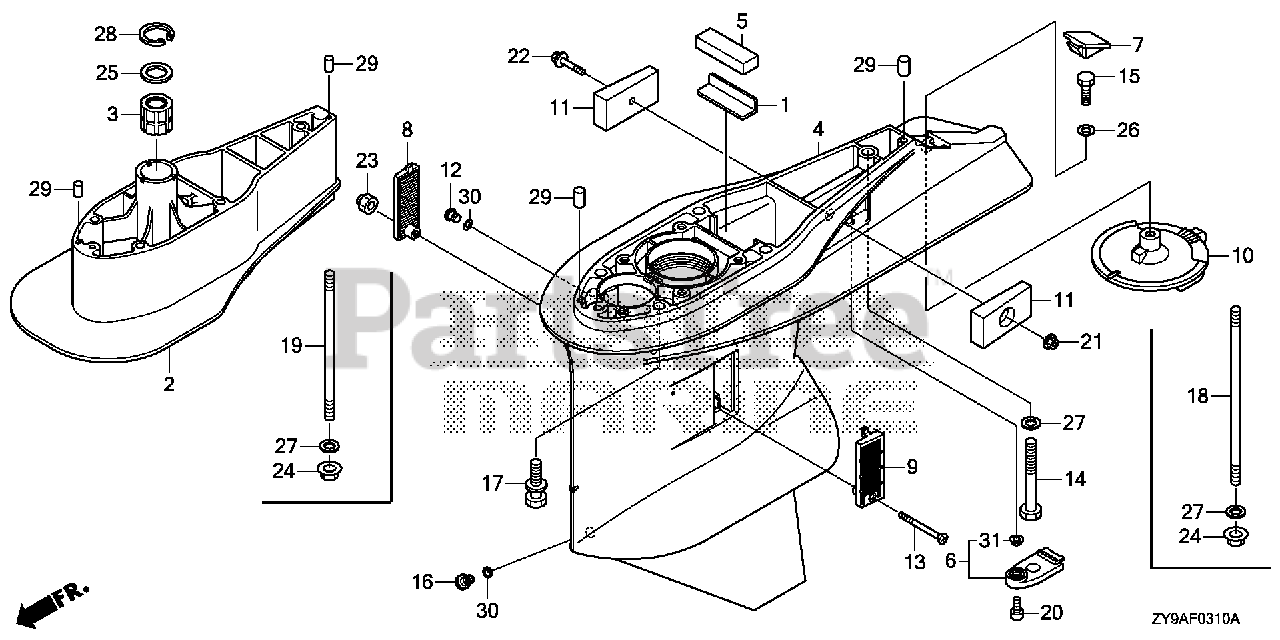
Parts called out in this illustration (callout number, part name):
1	PLATE, RUBBER SETTING
2	SEPARATOR, EXTENSION *NHB14M* (XL) (AQUA MARINE SILVER METALLIC)
3	BUSH, VERTICAL SHAFT
4	CASE, GEAR *NHB14M* (AQUA MARINE SILVER METALLIC)
5	GROMMET, GEAR CASE
6	COVER B, GEAR CASE
7	GROMMET, GEAR CASE
8	SCREEN, R. WATER
9	SCREEN, L. WATER
10	TAB, TRIM *NHB14M* (AQUA MARINE SILVER METALLIC)
11	METAL, ANODE
12	BOLT, OIL CHECK
13	SCREW, FLAT (5X55)
15	BOLT, HEX. (8X25)
16	BOLT, DRAIN PLUG
18	BOLT, STUD (10X202)
19	BOLT, STUD (10X164)
20	BOLT, SOCKET (6X16)
21	NUT, SELF-LOCK (6MM)
22	BOLT, FLANGE (6X35)
23	NUT, SELF-LOCK (5MM)
24	NUT, SELF-LOCK (10MM)
25	WASHER (26MM)
26	WASHER, PLAIN (8MM)
27	WASHER, PLAIN (10MM)
28	CIRCLIP (INNER) (40)
29	PIN, DOWEL (6X10)
30	O-RING (6.9X1.45)
31	COLLAR, DISTANCE (6.5X9X3)
